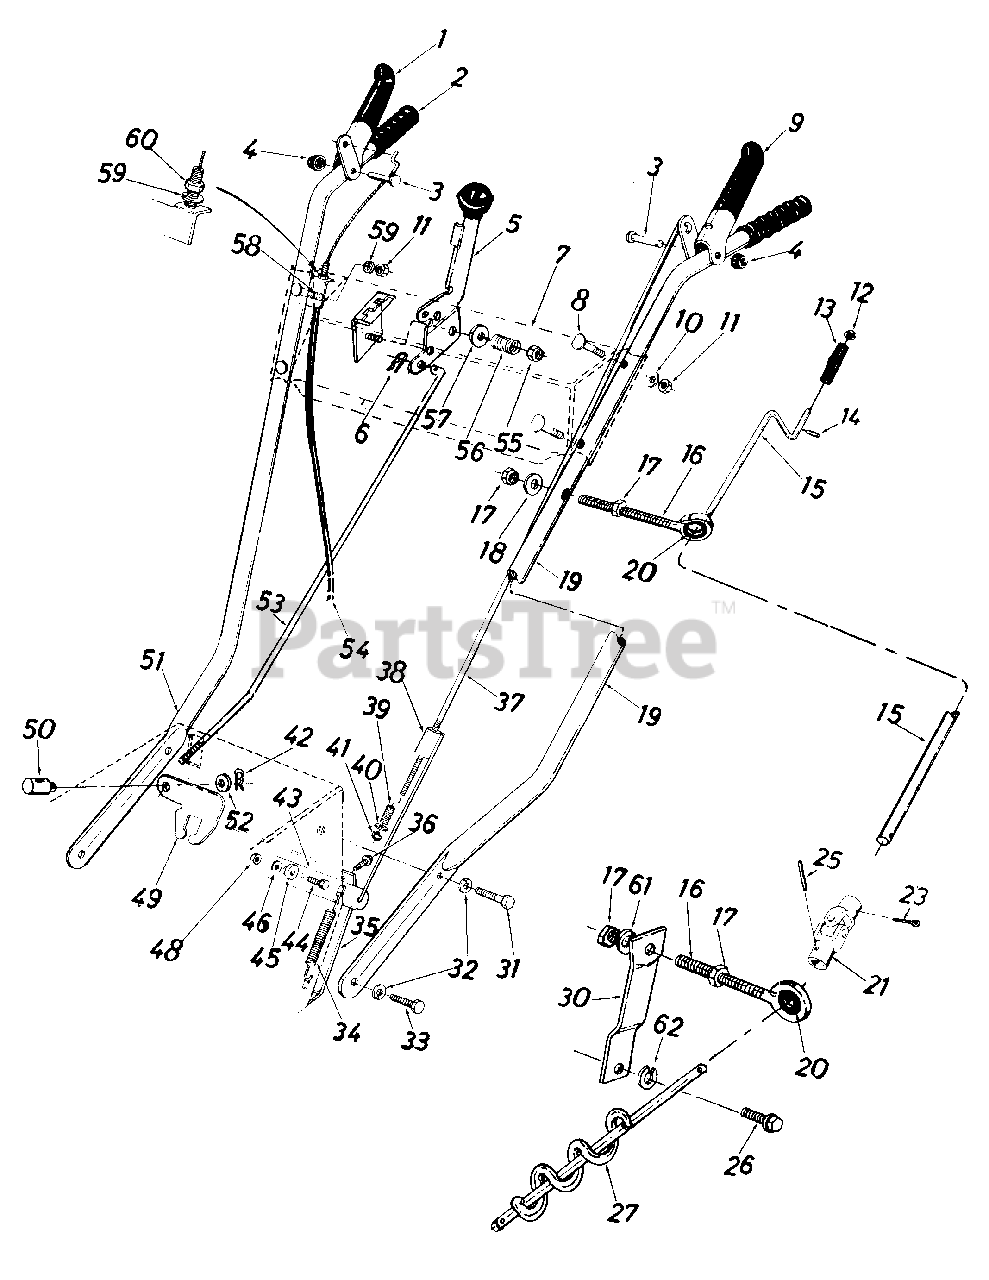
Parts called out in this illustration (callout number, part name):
1	Drive Clutch Grip Ass'y. (R.H.)
3	Clevis Pin .375" Dia.
4	Push Cap .375" Rod-Black
5	Shifting Handle Ass'y.
6	Int. Cotter Pin 5/16" Dia.
7	Handle Panel Ass'y.
8	Carriage Bolt 5/16-18 x 1.75" Lg.*
9	Auger Clutch Grip Ass'y. (L.H.)
10	Bell-Wash. .345" I.D. x .88" O.D.
11	Hex Nut 5/16-18 Thd.
12	Push Nut 3/8" Rod
13	Black Knob
14	Roll Pin 1/8" Dia.
15	Chute Crank .375" Dia. x 34.5" Lg.
16	Eye Bolt 5/16-18 x 3.0" Lg.
17	Hex Nut 5/16-18 Thd.
18	Bell-Wash. .34" I.D. x .88" O.D.
19	Handle-L.H.
20	Grommet
21	Joint Brkt. Ass'y.
23	Cotter Pin 3/32" Dia. x 1.00" Lg.
25	Spring Pin Roll 3/32" Dia. x .50" Lg.
26	Hex Self-Tap Scr. 3/8-16 x .75" Lg.
27	Chute Crank Ass'y.-R.H. 10" Lg.
30	Chute Crank Supt. Plate 1.25" x 4.12" Lg.
31	Hex Self-Tap Scr. 3/8-16 x .75" Lg.
32	Bell-Wash. .44" I.D. x .88 O.D.
33	Hex Self-Tap Scr. 3/8-16 x .75" Lg.
34	Extension Spring .38" O.D. x 3.25" Lg.
35	Frame Cover
36	Hex Self-Tap Scr. 1/4-20 x .50" Lg.
37	Clutch Rod .214" Dia. x 32.0" Lg.
38	Auger Clutch Rod Ass'y.
39	Compression Spring .39" O.D. x .75" Lg.
40	Fl-Wash. .28" I.D. x .75" O.D.
41	Hex Ins. L-Nut 1/4-20 Thd.
42	Cotter Pin 3/32" Dia. x .75" Lg.
43	Clutch Bracket
44	Hex Sems Bolt 5/16-18 x 1.0" Lg.
45	Shoulder Spacer
46	Fl-Wash. .34" I.D. x 1.12" O.D.
48	Hex L-Nut 5/16-18 Thd.
49	Shifting Bracket
50	Ferrule
51	Handle-R.H.
52	Fl-Wash. .344" I.D. x .62" O.D.
53	Shifting Rod
54	Drive Clutch Control Cable
55	Hex Ins. Jam L-Nut 3/8-24 Thd.
56	Compression Spring .60" O.D. x .88" Lg.
57	Bell-Wash. .40" I.D. x .88" O.D.
58	Cable Support Brkt.
59	L-Wash. 5/16" I.D.
60	Hex Jam Nut 5/16-24 Thd.
61	Bell-Wash. .345" I.D. x .88" O.D.
62	L-Wash. 3/8" I.D.
